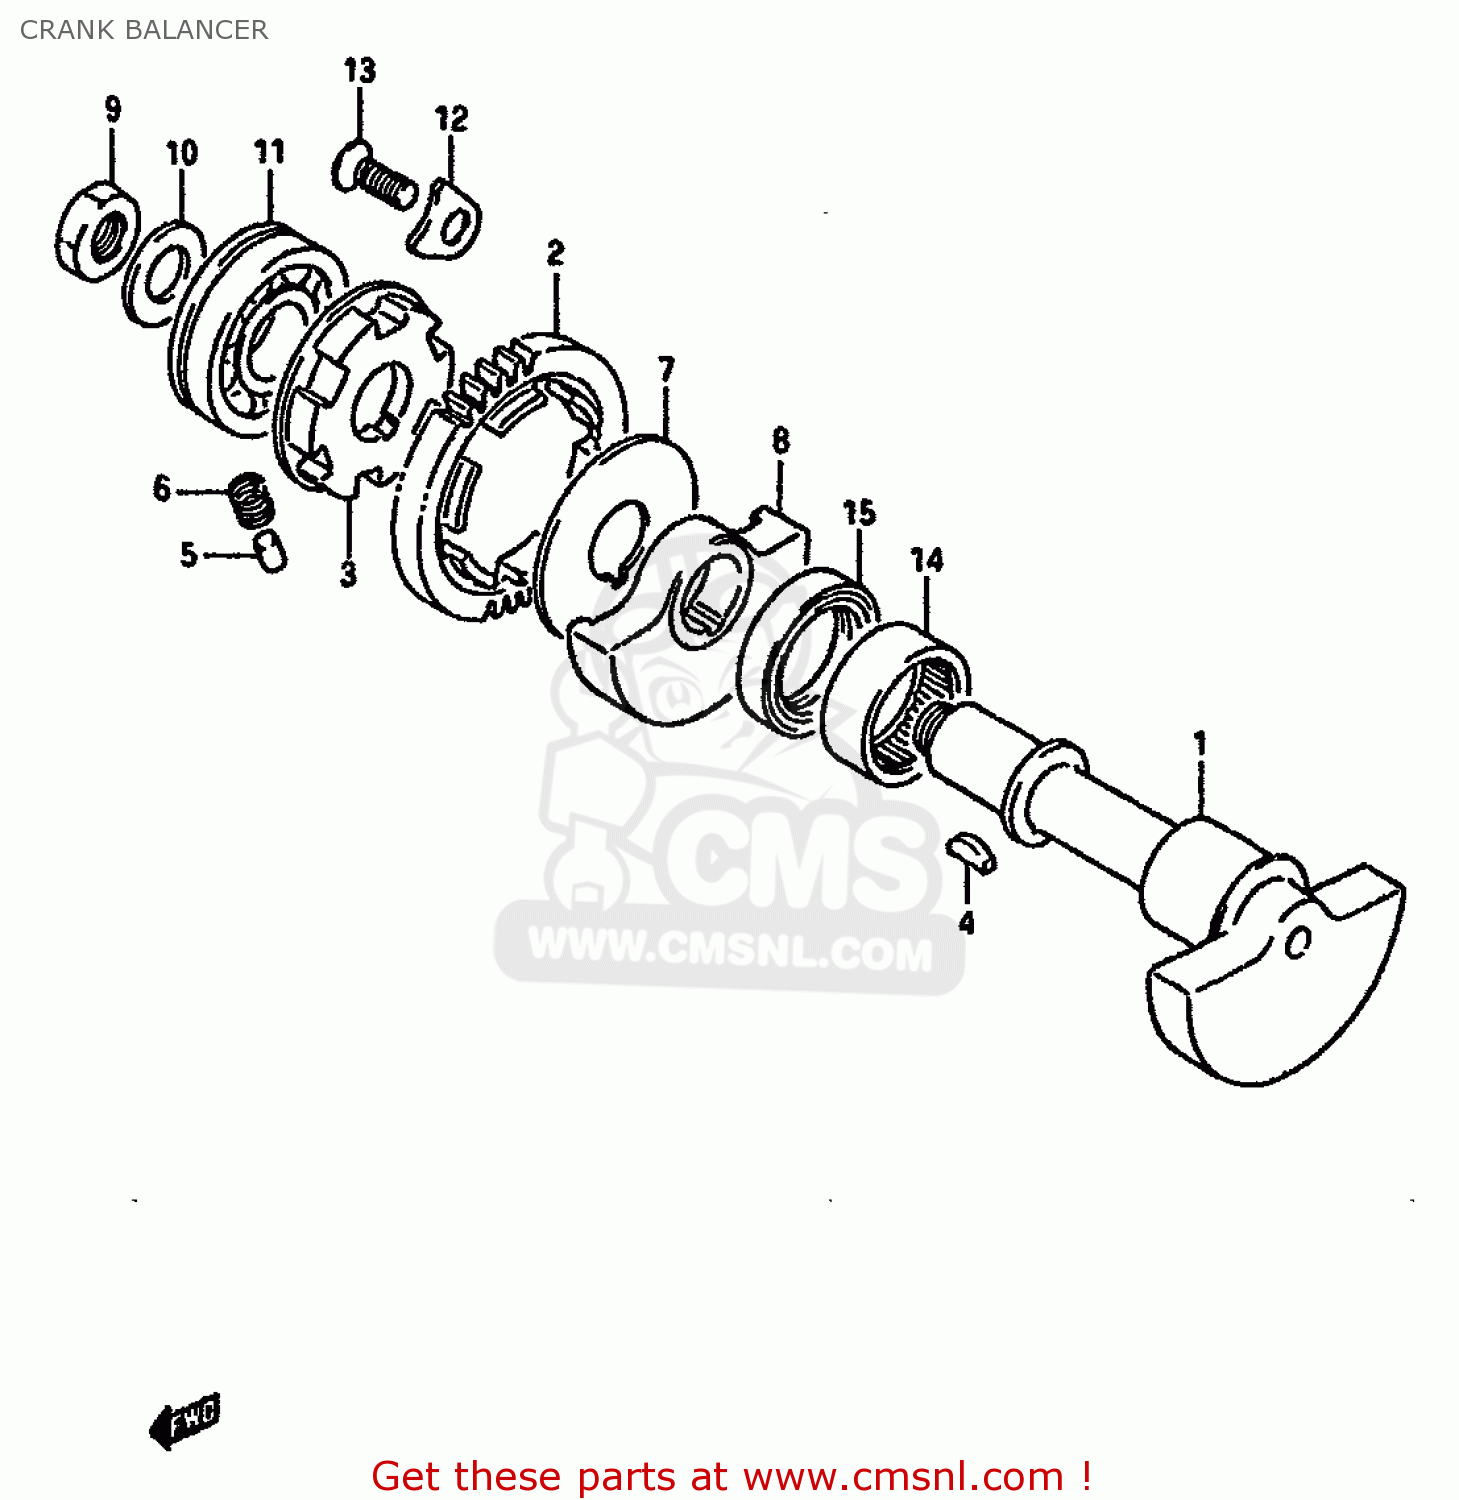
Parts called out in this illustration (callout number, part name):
1	BALANCER,CRANK
2	GEAR,CRANK BALANCER DRIVE
3	RACE,CRK BAL DRIVEN GEAR INNER
4	KEY
5	PIN
6	SPRING
7	WASHER
8	WEIGHT,CRANK BALANCER
9	NUT
10	WASHER
11	BEARING(20X52X15)
12	RETAINER,CRANK BALANCER SHAFT
13	SCREW
14	BEARING(28X35X16)
15	SEAL,OIL(28X40X8)
